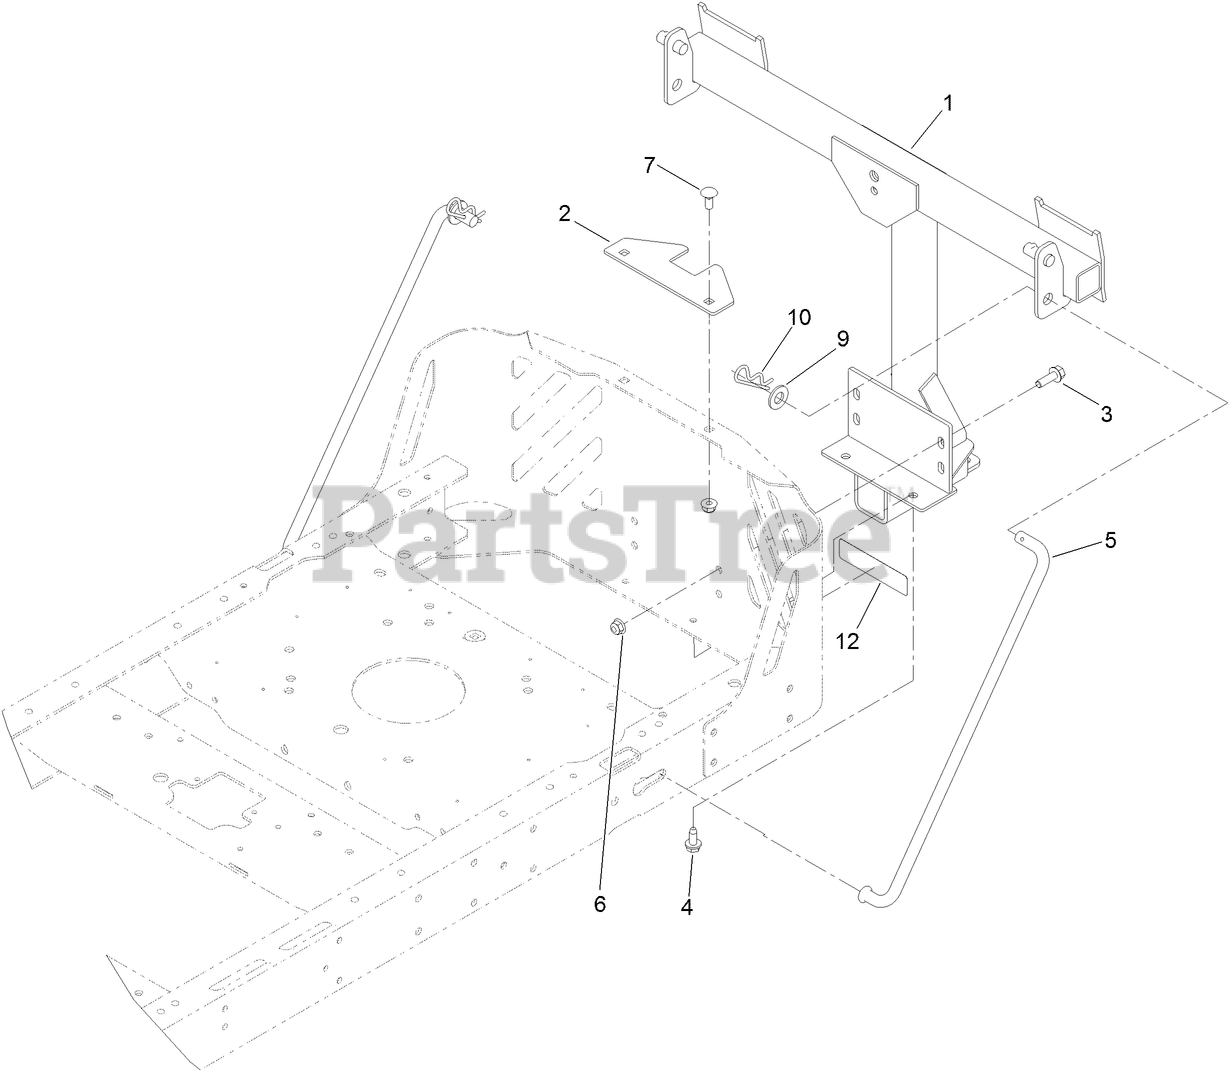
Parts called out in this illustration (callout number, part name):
1	FRAME-PIVOT
2	BRACKET-STABILIZER
3	SCREW-HHF
4	SCREW-HWHTF
5	ROD-SUPPORT
6	NUT-HF, NI
7	BOLT-CARR
9	WASHER-FLAT
10	PIN-HAIR
